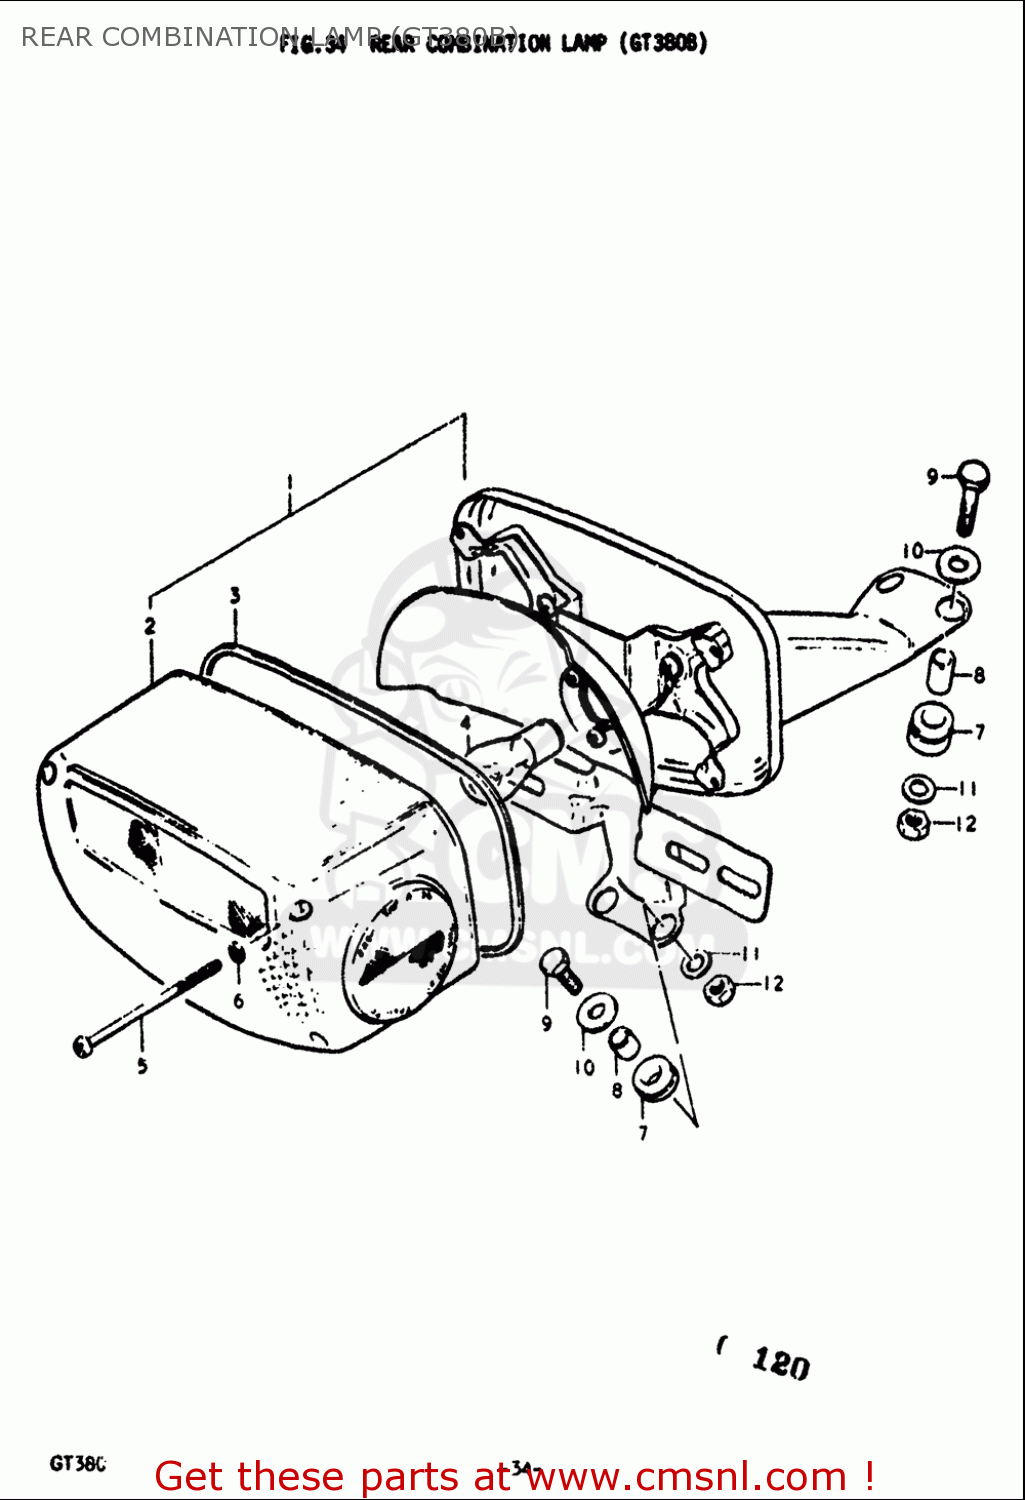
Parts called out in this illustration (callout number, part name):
2	LENS
3	GASKET (NAS)
4	BULB(12V23W)
6	GASKET (NAS)
7	CUSHION
8	SPACER
9	BOLT
10	WASHER(6.5X20X1.2)
11	WASHER
12	NUT
